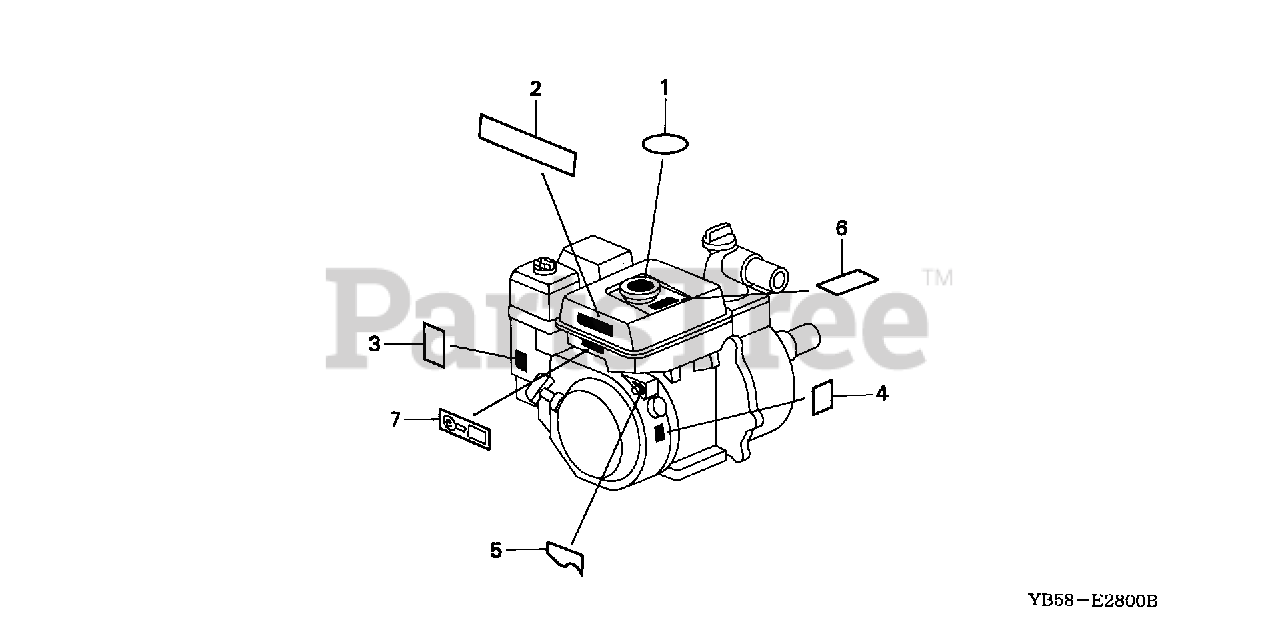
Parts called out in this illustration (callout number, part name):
1	MARK, CAUTION
2	LABEL, CAUTION (ENGLISH, ETC.)
3	MARK, CHOKE
4	LABEL, SPECIFICATION (5.5HP)
5	MARK, OIL ALERT (EXTERNAL)
6	MARK, OIL ALERT (ENGLISH)
7	LABEL, E-SPEC (15.5X27.5)
